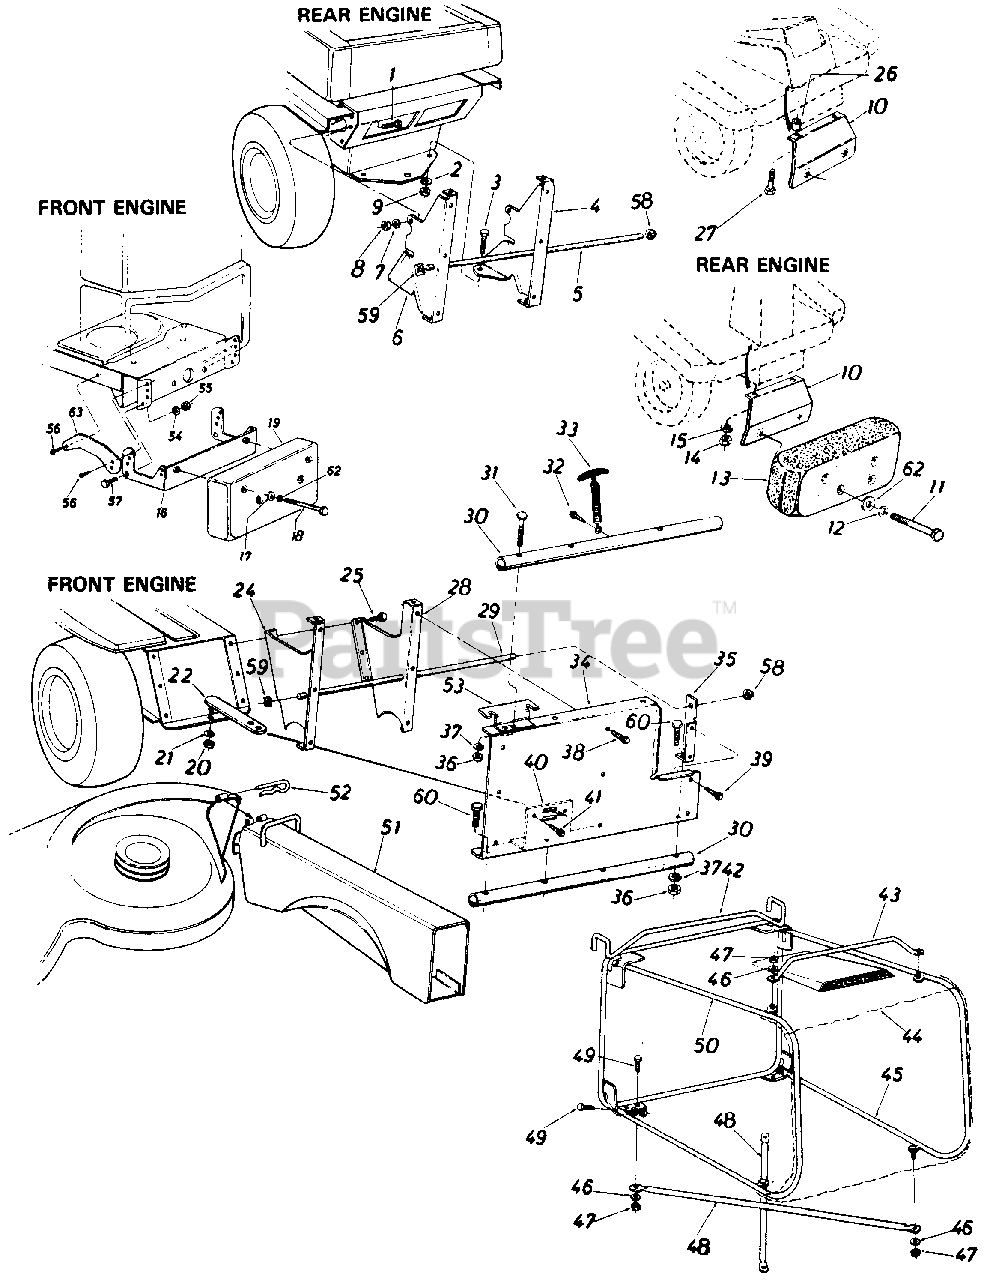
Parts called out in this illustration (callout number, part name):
1	Hex Bolt 5/16-18 x 1-00" Lg.*
2	L--Wash. 5/16" I.D.*
3	Hex Bolt 5/16-18 x 1.00"
4	Catcher Support Brkt R-H
7	L. Wash. 5/16" I.D.*
8	Hex Nut 5/16 18 Thd.*
9	Hex Nut 5/16-18 Thd.*
10	Counterweight Bracket
11	Hex Bolt 3/8-16 x 4.5" Lg.*
12	Belleville Wash. .400" I.D. x.88" O.D.
13	Front Counterweight 381bs.
14	Hex Nut 5/16-18 Thd.*
15	L.-Wash. 5/16" I.D.*
16	Counterweight Bracket
17	Belleville Wash. .400" I.D. x.88" O.D.
18	Hex Bolt 3/8-16 x 4.5" Lg.*
19	Front Counterweight 38 Lbs.
20	Hex Jam Nut 1/2-13 0 Thd.*
21	L.-Wash. 1/2" I.D.*
25	Hex Wash. Hd. Self Tap Scr. 5/16-18 x .75 Lg.*
26	Spacer.380" I.D. x 1.00" O.D. x.320" Lg.
27	Not Part of Kit
28	Catcher Support Brk't.-R . H .
31	Curved Carrlage Bolt 5/16-18 x 1.75" Lg.
32	Hex"AB"-TapScr. 1/4" x .62" Lg.
33	Hood Latch Ass'y.
34	Grass Catcher Adapter
35	Grass Catcher Support Brkt. R.H.
36	Hex Nut 5/16-18 Thd.*
37	L.-Wash. 5/16" I.D.*
38	Hex Wash. Hd. Self Tap Scr. 1/4-20 x .50" Lg.
39	Hex Wash. Hd. Self Tap Scr. 1/4-20 x .50" Lg.
40	Hitch Bracket
41	Hex Wash. Hd. Self Tap Scr. 1/4-20 x . 50" Lg.
42	Grass Bag Frame Ass'y.
43	Grass Catcher Handle 26.75
44	G rass Catcher Bag
47	Hex L.-Nut 1/4-20Thd.
48	Bottom Cross Brace 30.36" Lg. *
49	Hex Bolt 1/4-20 x .62" Lg. *
52	Not Part of Kit
53	15995 0 GrassCatcherSupportPlate
54	L.-Wash. 7/16" I.D.*
55	Hex Nut 7/16-20 Thd.*
56	Hex AB Tap Scr. 5/16-18 x l '9
57	HexBolt 7/16-20x 1.00" Lg. *
58	Push Cap
59	Speed Nut
60	Hex Bolt 5/16-18 x 1.75 Lg. *
60	Spacer
62	Fl.-Wash. .390" I.D. x 1.12" O.D. x .187 Thk.
63	Tie Strap
